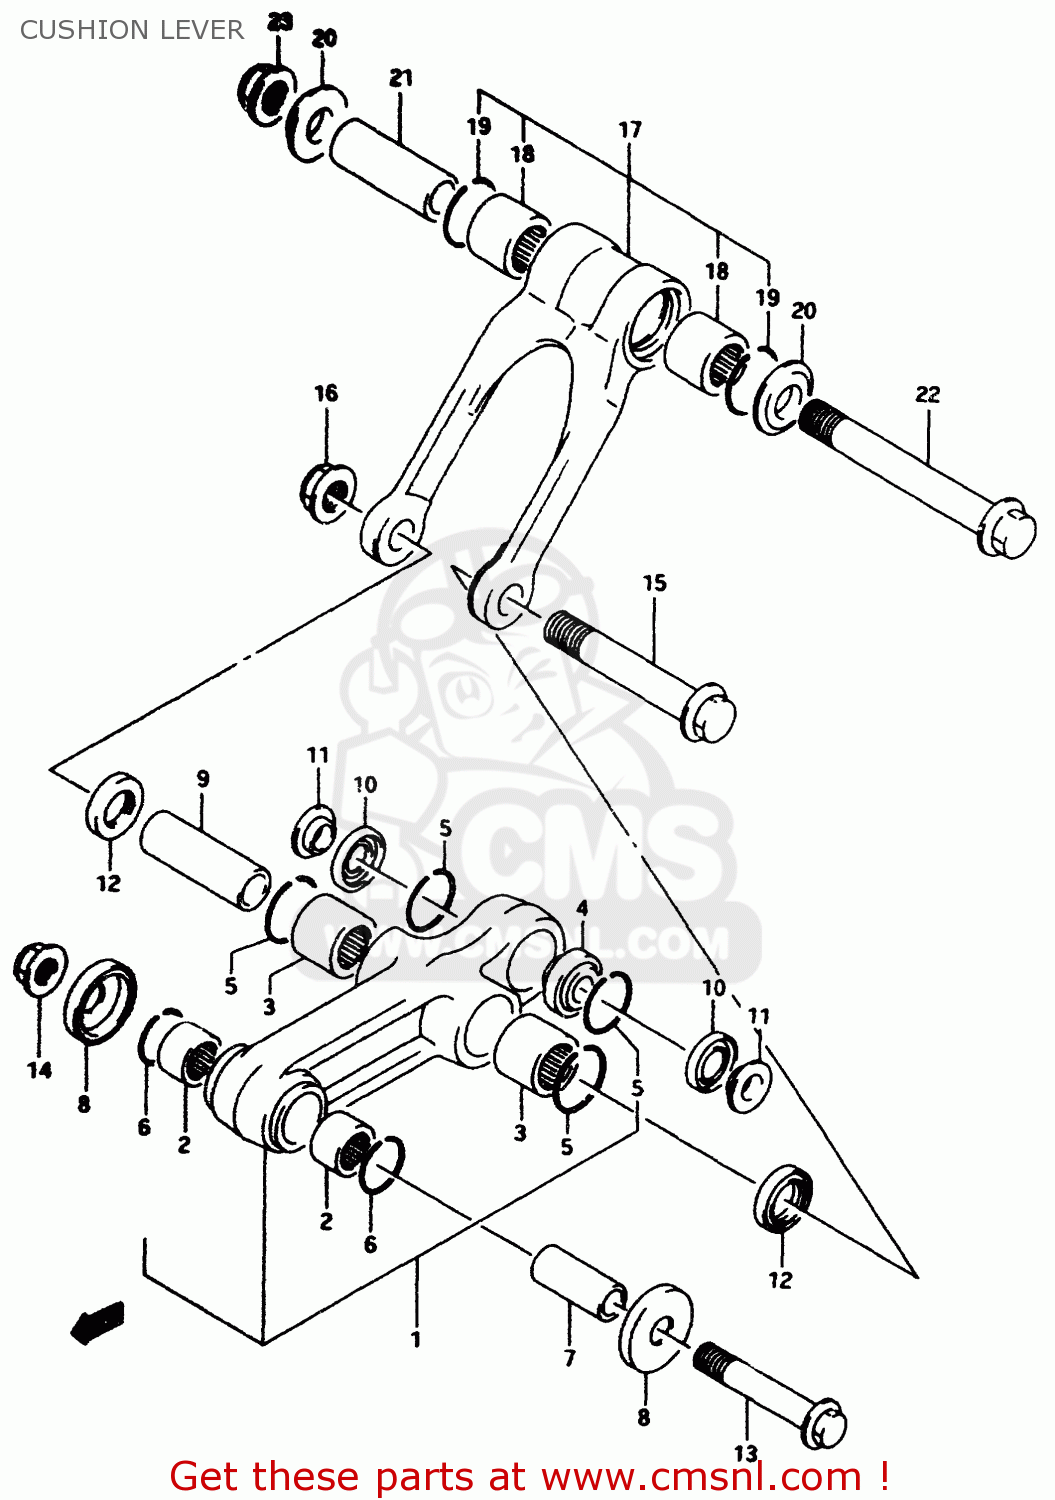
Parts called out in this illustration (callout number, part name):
1	LEVER SET,RR CUSHION
2	BEARING(14X20X12)
3	BEARING(17X24X20)
4	BEARING,RR CUSHION LEVER
5	RING,STOPPER
6	CIRCLIP,PISTON PIN
7	SPACER,RR CUSHION LEVER FR
8	SEAL,RR CUSHION LEVER FR DUST
9	SPACER,RR CUSHION LEVER CTR
10	SEAL,RR CUSHION LEVER RR DUST
11	SPACER,RR CUSHION LEVER RR
12	SEAL,OIL(17X24X3)
13	BOLT,RR CUSHION LEVER FR
14	NUT
15	BOLT,RR CUSHION LEVER CTR
16	NUT 12MM
17	ROD SET,REAR CUSHION,LEFT
18	BEARING(17X24X20)
19	RING,STOPPER
20	SPACER,RR CUSHION ROD SIDE
21	SPACER,RR CUSHION ROD
22	BOLT,RR CUSHION ROD
23	NUT 12MM
